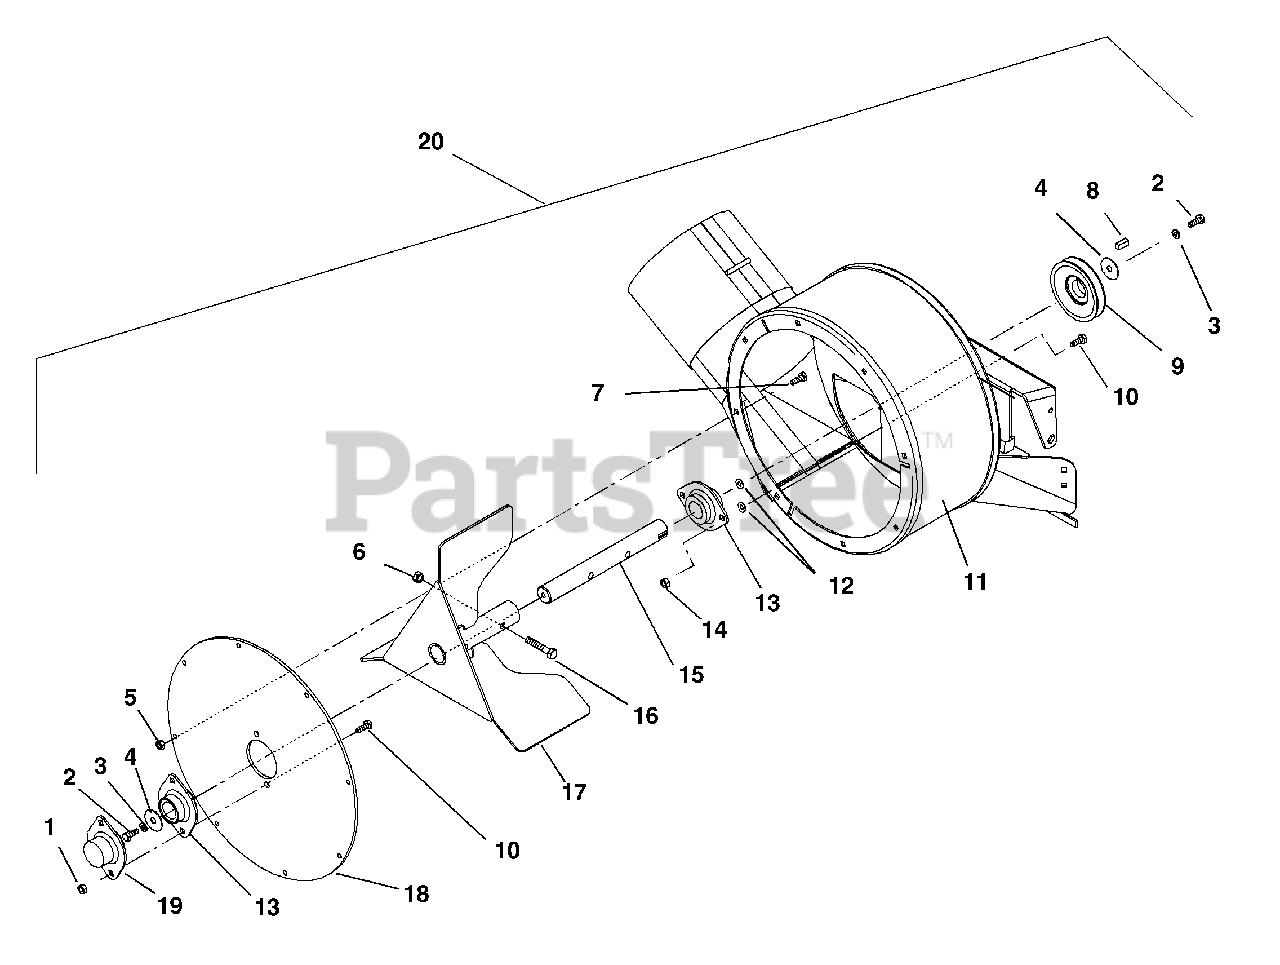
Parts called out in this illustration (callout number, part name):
1	Nut-Locking-Nylon .312-18
2	Bolt-Hex .25-20 x .75 Grade 5
3	Washer-Locking .25 x .062 Regular
4	Washer-Flat-Steel Washer-Flat-Steel .265 x 1.370 x .179
5	Nut-Locking-Top-Flange .25-20
6	Nut-Locking-Center .31-18
7	Bolt-Round Head Square Neck .25-20 x .50 Grade 5
8	Key-Square .25 x .38 x .25
9	Pulley-Driven 3.50 Dia.
10	Bolt-Hex .31-18 x 1.00 Grade 5
11	Weldment, Blower Housing
12	Washer-Flat-Steel .312 x .734 x .06
13	Bearing-2 Bolt x 1.00 Shaft
14	Nut-Locking-Top-Flange .31-18
15	Shaft-Impeller
16	Bolt-Hex .31-18 x 1.75 Grade 5
17	Impeller Complete
18	Cover-Bearing Support
19	Cover-Bearing
20	Assembly, Blower Housing
